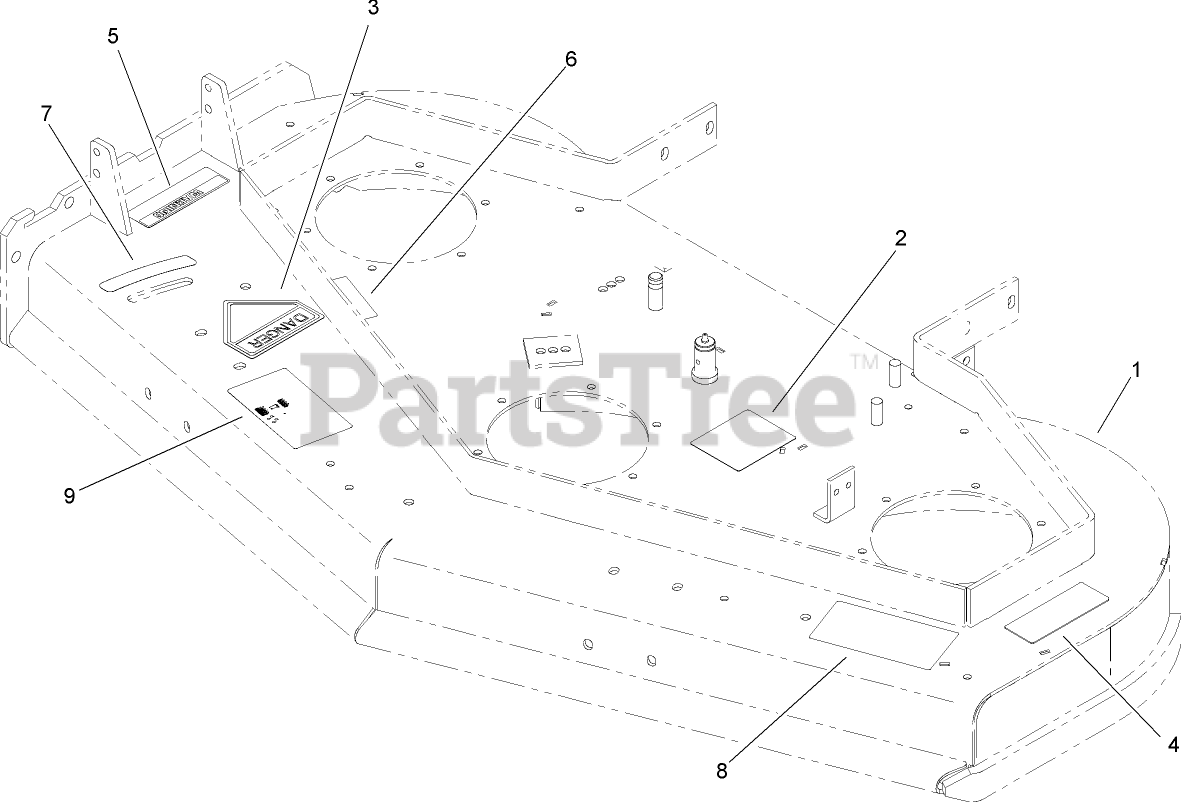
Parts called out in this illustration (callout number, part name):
1	52 INCH DECK ASM
2	DECAL-ROUTING, BELT
3	DECAL-DANGER
4	DECAL-TORQUE, BOLT
5	DECAL-WARNING
6	DECAL-COVER, MISSING
7	DECAL-SETTING, BAFFLE
8	DECAL-DANGER, THROWN OBJECT
9	DECAL-ADJUSTMENT, BAFFLE
